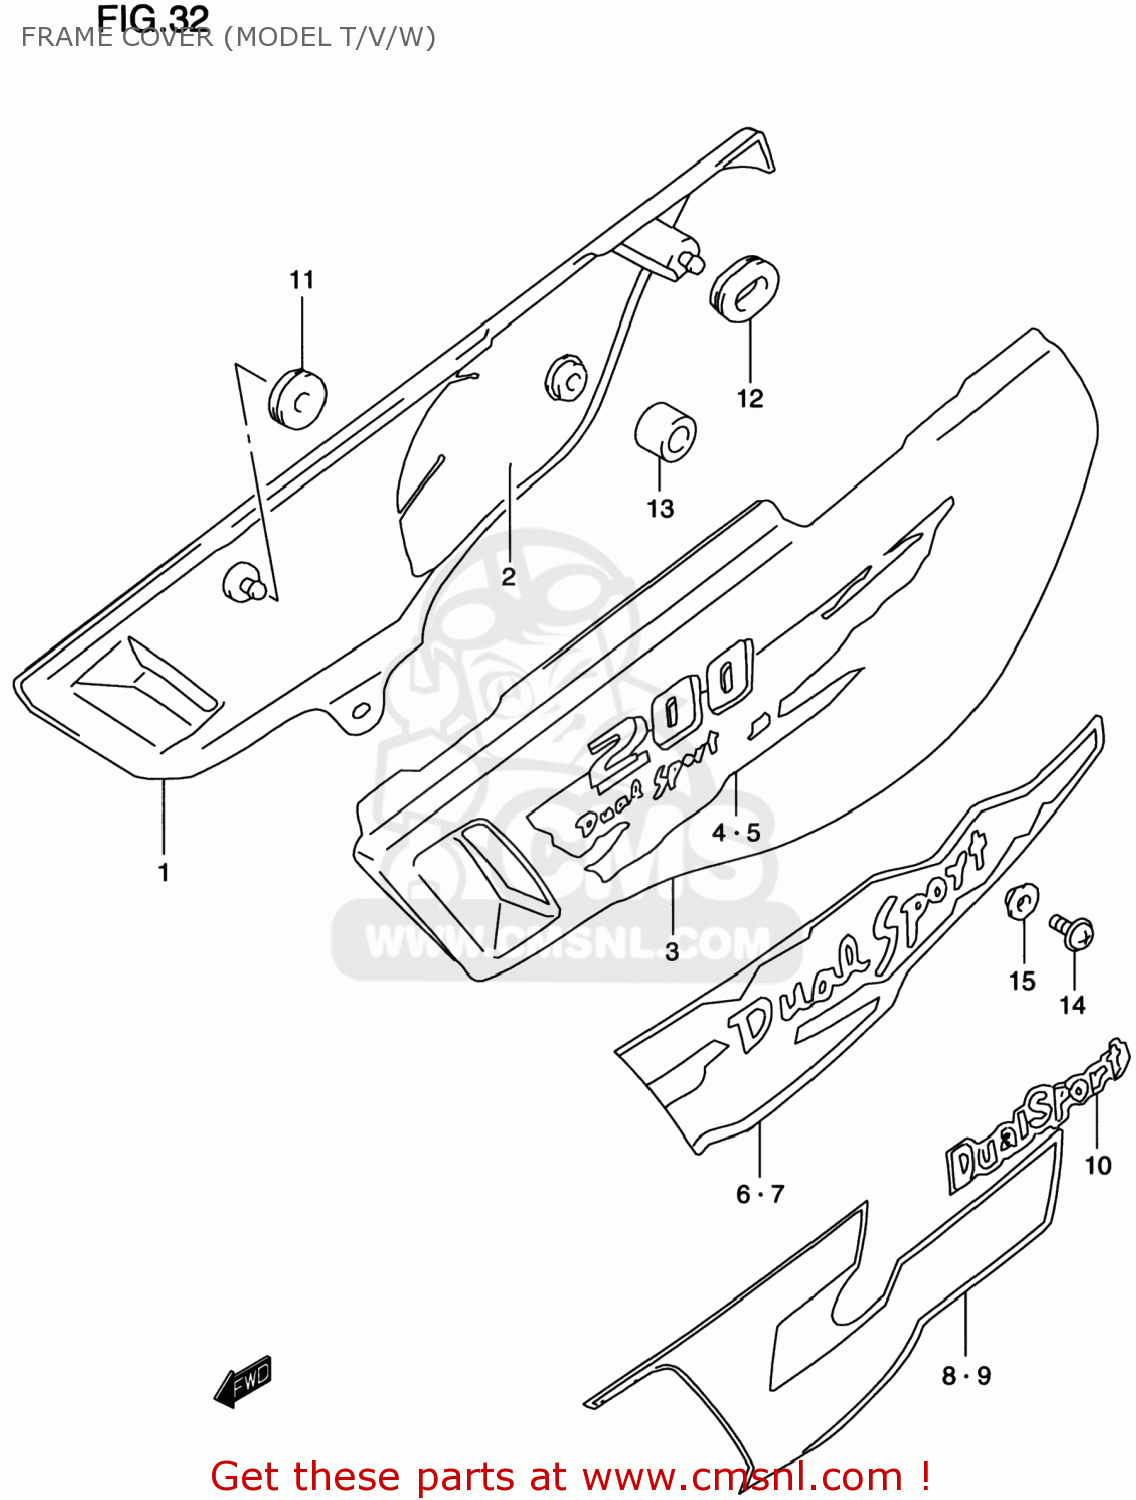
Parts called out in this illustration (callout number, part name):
1	COVER,FRAME,R(WHITE)
2	SHIELD,FRAME COVER,R
3	COVER,FRAME,L(WHITE)
4	TAPE,FRAME COVER,RIGHT
5	TAPE,FRAME COVER,L
6	TAPE,FRAME COVER,RIGHT
7	TAPE,FRAME COVER,LEFT
8	TAPE,FRAME COVER,RIGHT
9	TAPE,FRAME COVER,LEFT
10	EMBLEM,FRAME COVER
11	CUSHION
12	CUSHION
13	CUSHION
14	SCREW(6X16)
15	WASHER
